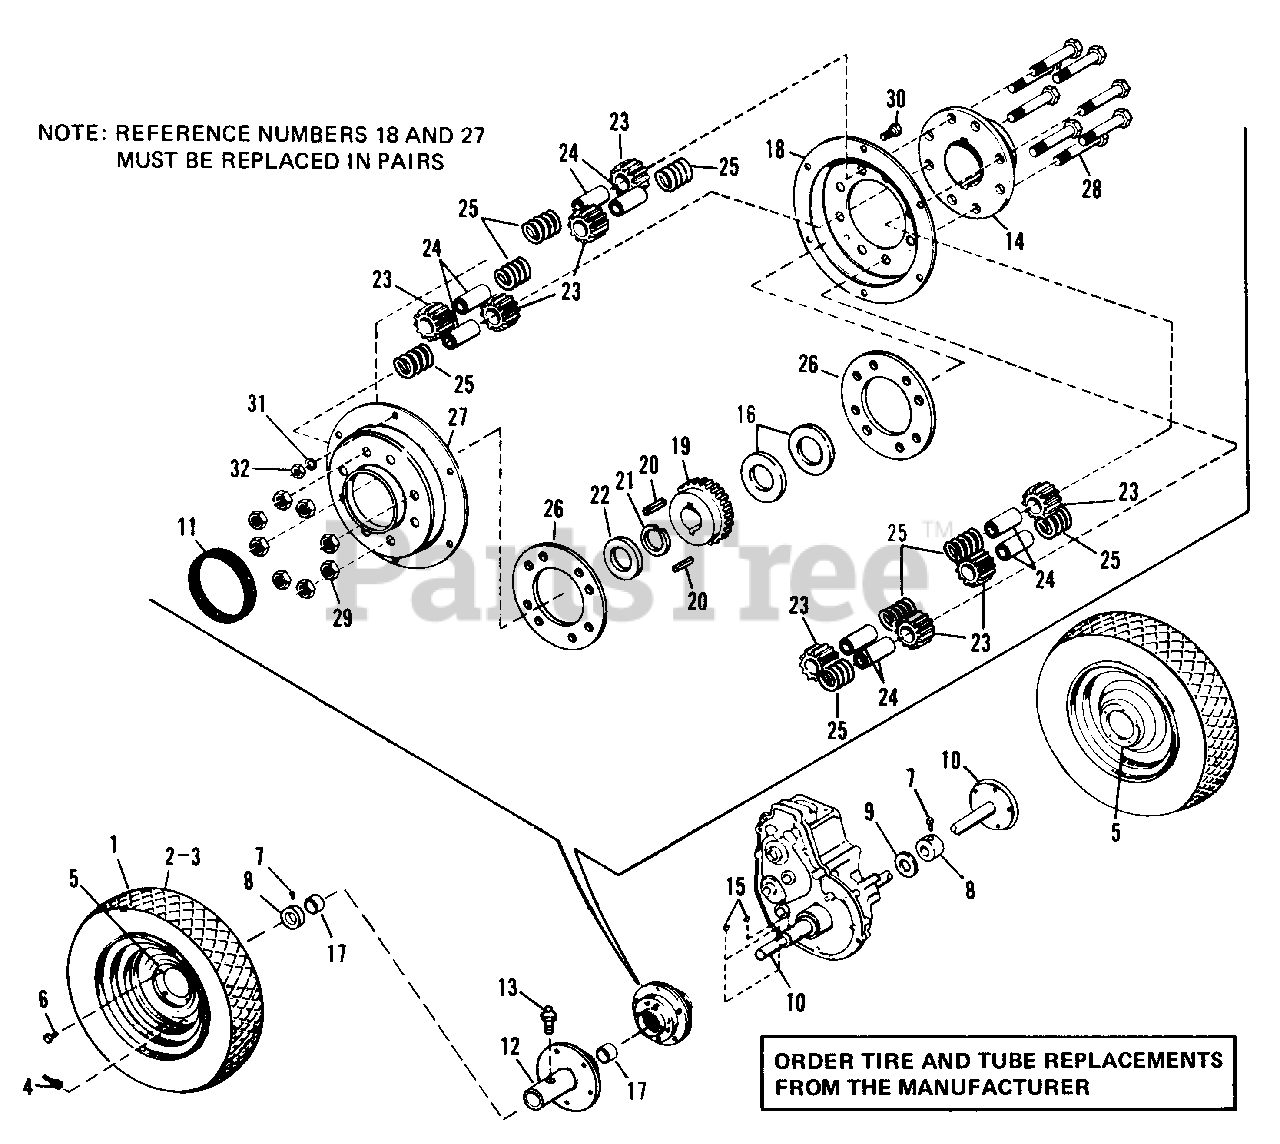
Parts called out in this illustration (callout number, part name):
1	Wheel & Tire Assy.
4	Valve Stem
5	Wheel Drive
7	Set Screw, 5/16"-18 x 3/8"
8	Axle Collar
11	Differential Cover Seal
12	R.H. Wheel Hub Assy.
13	Grease Fitting
14	Differential Carrier
16	Axle Washer
18	Differential Cover
19	Differential Gear
20	Hi-Pro Key
21	Retaining Ring
22	Axle Washer
23	Differential Pinion
24	Differential Pinion Spindle
26	Ring Spacer
27	Differential Cover
28	Hex Capscrew, 3/8"-16 x 2-1/2"
29	Full Hex Lock Nut, 3/8"-16
30	Hex Capscrew, 1/4"-20 x 5/8"
31	Lockwasher, 1/4"
32	Full Hex Nut, 1/4"-20
